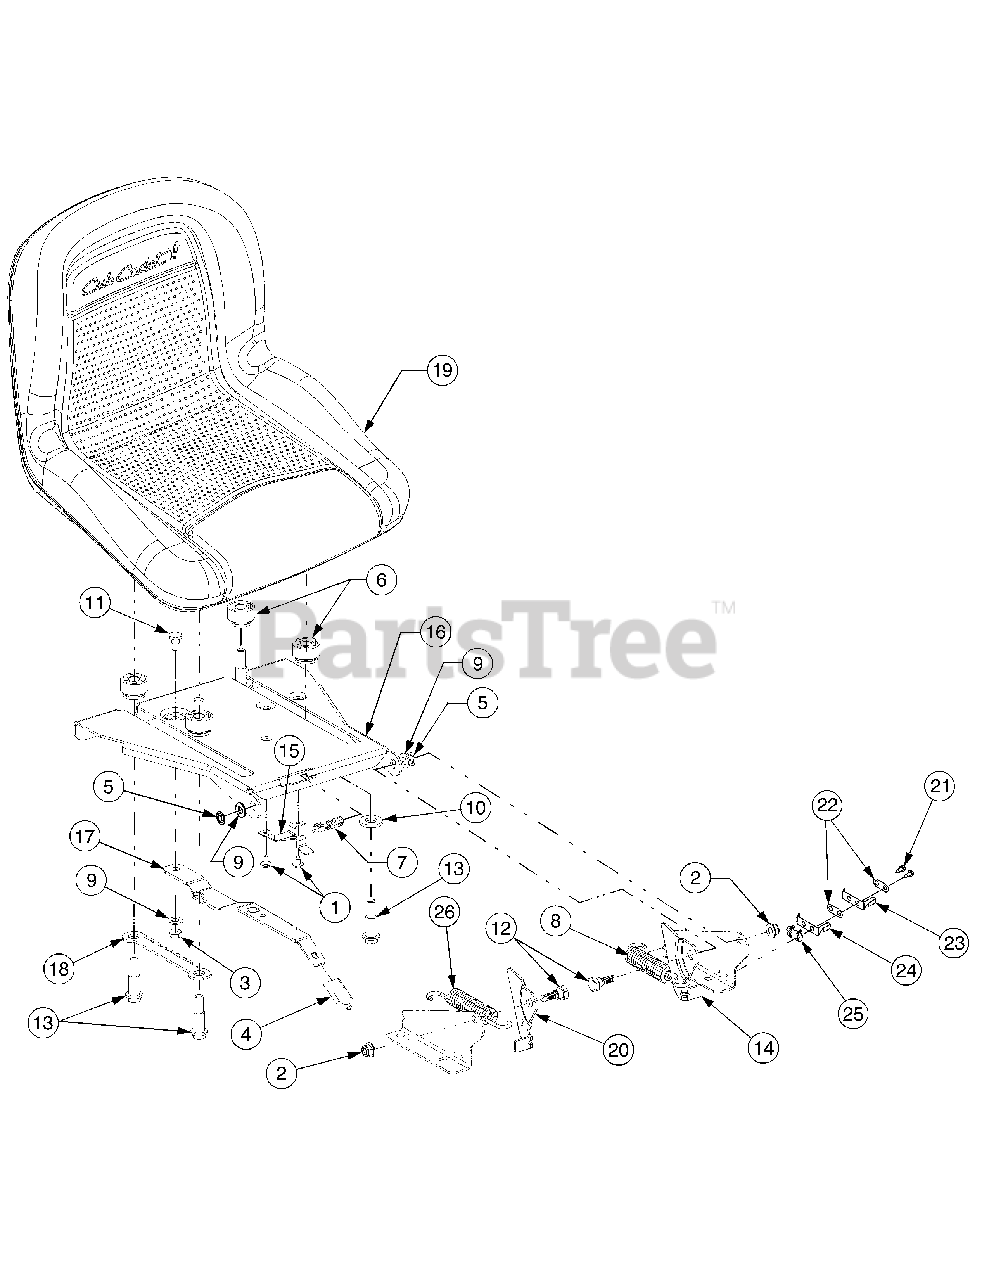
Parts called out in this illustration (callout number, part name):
1	Screw Hex Wash Hd., #10-16, .375
2	Nut, Flange Insert Lck, 5/16-18, Gr5
3	Nut, Flange Lock, 1/4-20
4	Grip, Seat Adjustment (Yellow)
5	Nut, Speed, .3125 ID
6	Spacer, Seat, Adjustment
7	Spring, Compression .41 OD x 1.5
8	Spring, Extension, .84 Dia x 4.6 Lg
9	Washer, Flat, .344 x .688 x .065
10	Washer, Flat, .531 x 1.062 x .134
11	Screw, Shoulder, .34 x .285, 1/4-20
12	Shoulder, Screw .437 x .286 Lg
13	Screw, Shoulder, .50 x.93
14	Bracket, Seat Lift
15	Stop, Seat, Adjustment
18	Selector, Seat, Adjustment
19	Seat, Mid-back, V-1480
19	Graphic, Made in USA
19	Graphic, Cub Cadet
20	Bracket, Seat Lift
21	Screw, #8-18 x.50
22	Plate, Insulator
23	Spring Switch, Outer
24	Spring Switch, Inner
25	Plate, Insulator Boss
26	Spring, Extension, .815 x 4.775
